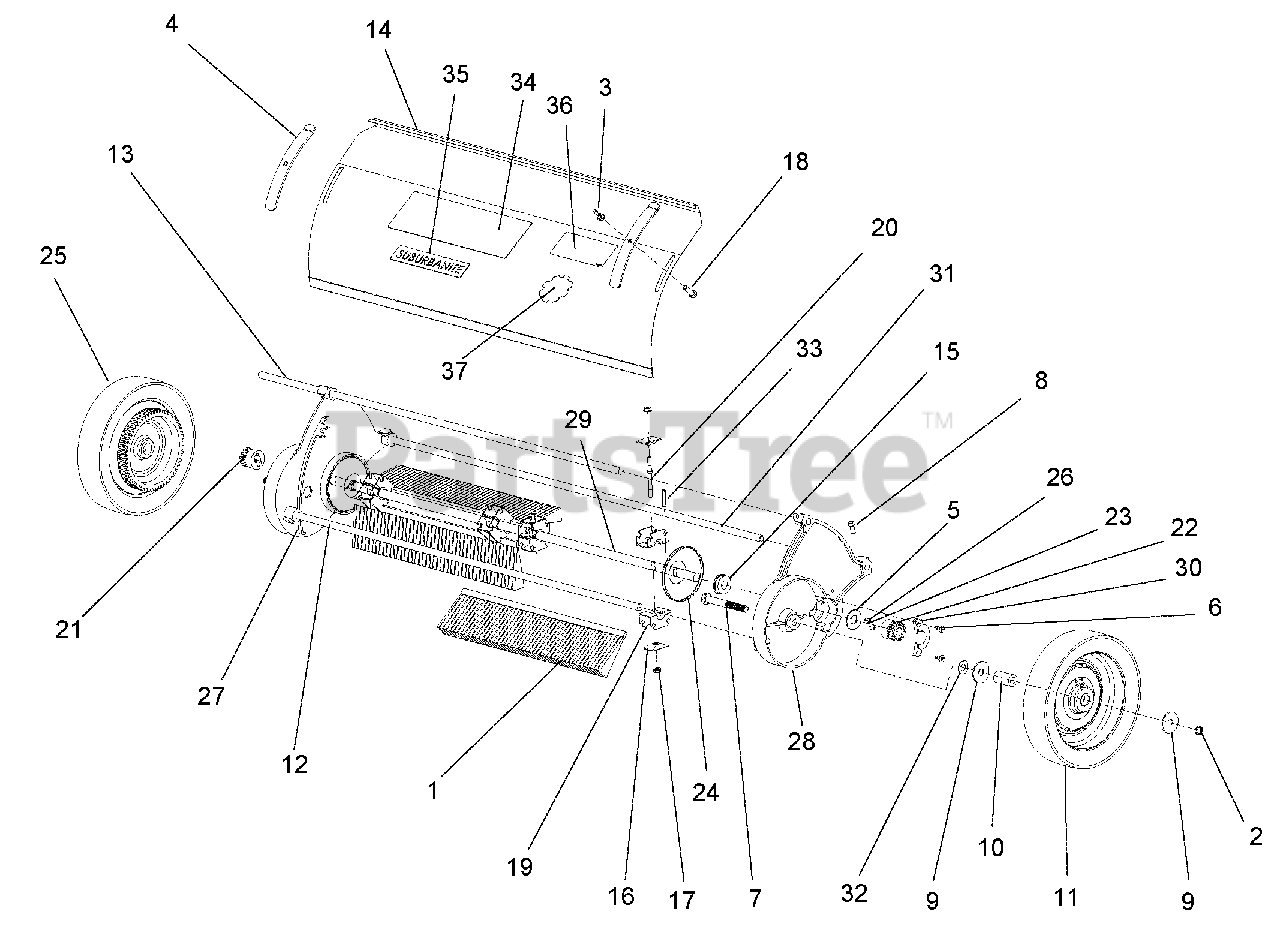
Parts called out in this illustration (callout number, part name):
1	Brush Assembly
1A	Brush Kit (includes mounting hardware)
2	Nut, 1/2-20 Hex Nyloc
3	Nut, 5/16-18 Wing
4	Clamp, Hood
5	Washer, .656 x 1.50 x .06 Flat
6	Screw, 1/4-20 x .5/8 Flat Hd.
7	Bolt, Axle
8	Set Screw, Square Hd.
9	Washer, 5.16 x 1.625 x .075 Flat
11	Wheel Hub
12	Tie Rod, Zinc Plated
13	Tie Rod
14	Hood with Decals, SU, Gravely
15	Bearing, .625 x .150 Flange Radial
16	Clamp, Brush Strip
17	Nut, 1/4-20 Flanged
18	Bolt, 5/16-18 x 1 Hex 5
20	Stud, Plated Zinc
21	Pinion, Right
22	Pinion, Left
22A	Pinion Kit (includes items 21, 22, 23 & 26)
23	Dowel Pin, .1875" OD x .4375"
24	Dust Cover, Zinc Plated
25	Tire Only
25A	Tire Assembly (includes items 11 & 25)
26	Pawl Spring
27	Side Plate, Right
28	Side Plate, Left
29	Shaft, Reel
30	Casting, Cover Pinion
31	Adjust Tube, 1/2 x .065 Zinc Plated
32	Washer, .656 x 1.50 x .06 Fiber
33	Pin, Roll 3/16 x 1.0
34	Decal, Gravely Logo
35	Decal, Suburbanite
36	Decal, Danger Read Manual
37	Decal, Gravely, Heritage-Small
